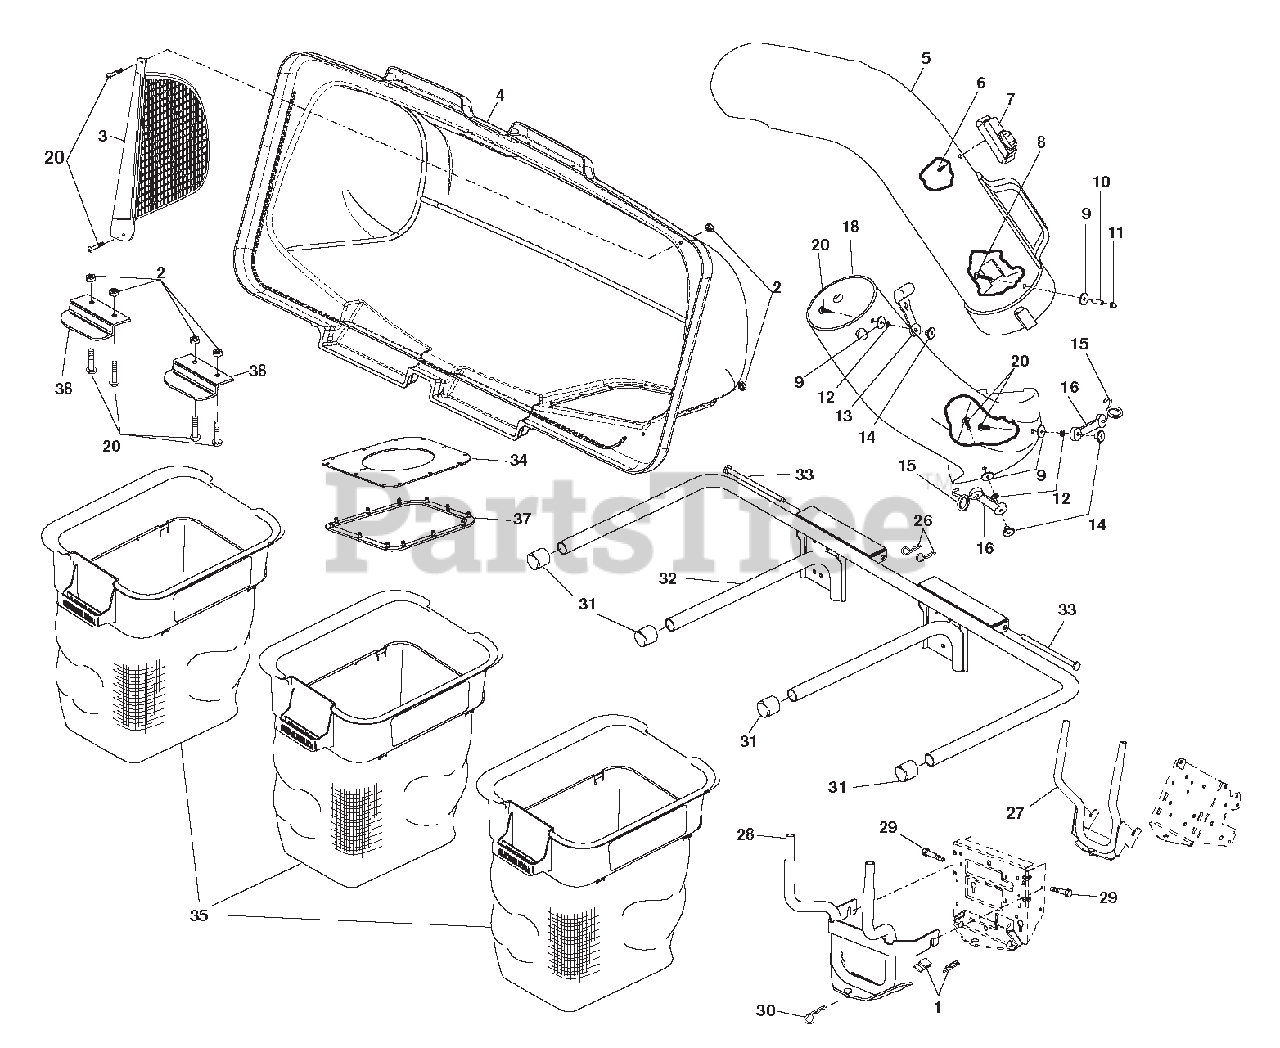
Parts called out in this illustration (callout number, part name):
1	ADAPTER
2	NUT, CROWN LOCK #10-24
3	Screen, Cover
4	Cover Assembly (Includes 34, 3
5	CHUTE, UPPER
6	Screw, Special #10-14x1/2
7	FULL BAG INDICATROR
8	SCREW #10-24 X 1-1/8"
9	WASHER 3/16 X 3/4
10	SPACER, SPLIT
11	ACORN NUT #10-24
12	LOCK WASHER
13	CHUTE LATCH, HUSQ BAGGER
14	Nut, Weld
15	LATCH, HOOK
16	RUBBER, LATCH
18	CHUTE, LOWER
20	SCREW #10-24 X 5/8
26	RETAINER.SPRING
27	Support Assembly
28	SUPPORT ASSEMBLY
29	Shoulder Bolt,Self Tapping
30	Spring, Retainer
31	Plug, Tubing End
32	BAGGER, FRAME
33	Pin, Hinge
34	Gasket, Cover
35	Container
37	Seal, Cover
38	Latch Handle, Cover
40	SCREW #10-24 X 1/2
